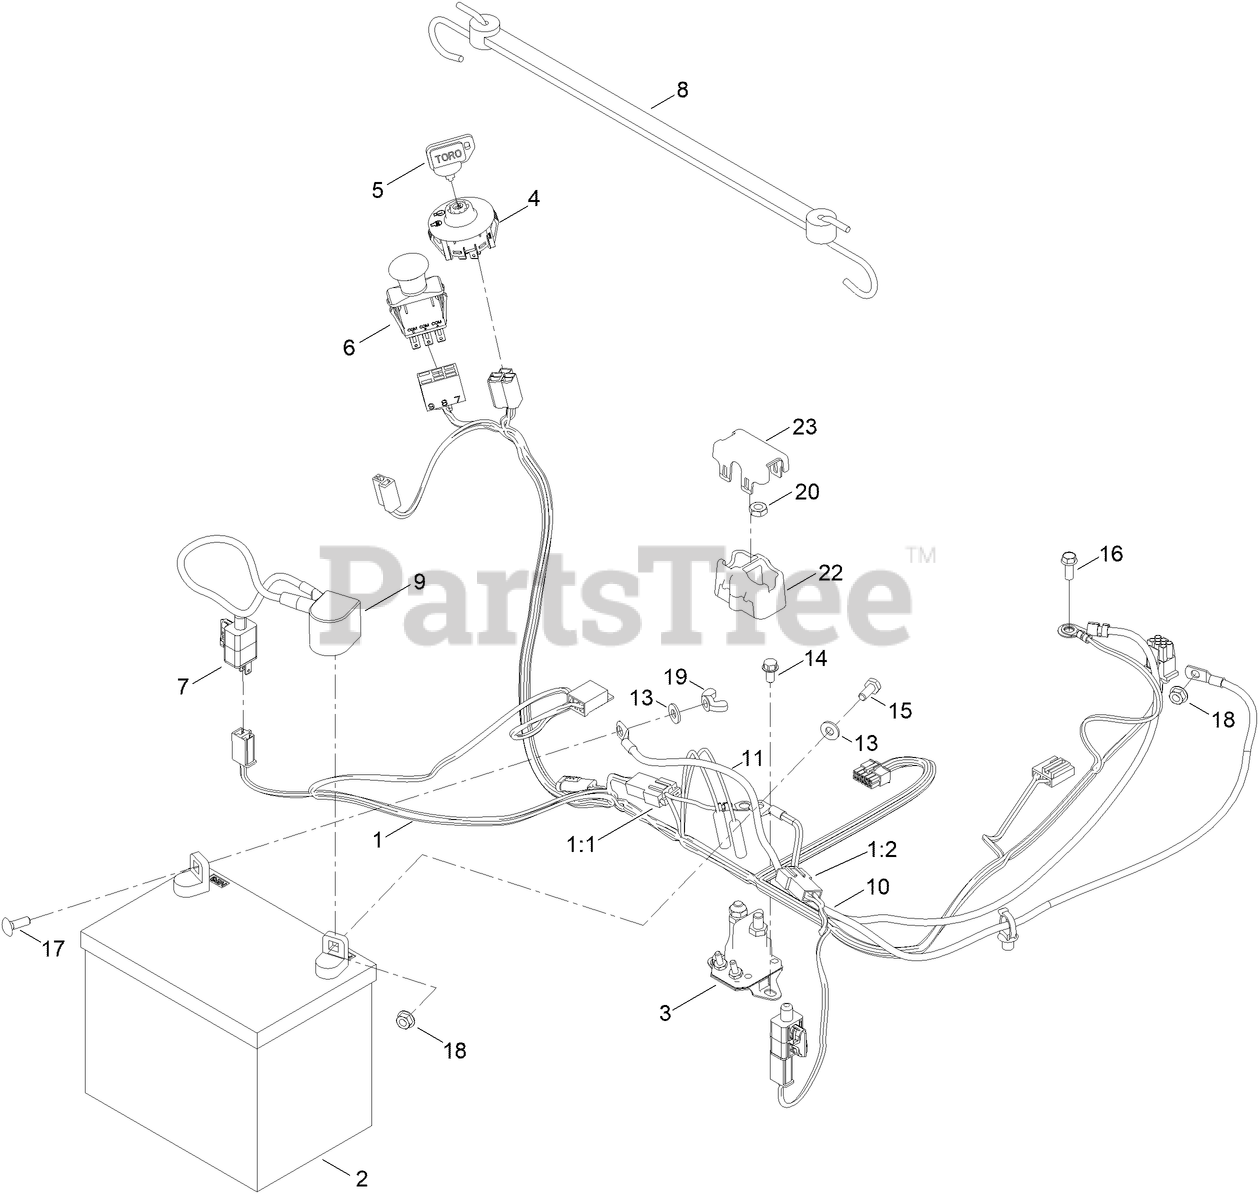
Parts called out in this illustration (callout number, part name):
1	HARNESS-WIRE
1:1	FUSE-BLADE, 15 AMP
1:2	FUSE-BLADE, 25 AMP
2	BATTERY
3	SOLENOID
4	SWITCH-IGNITION
5	KEY-IGNITION
6	SWITCH-PTO
7	SWITCH
8	STRAP-RUBBER
9	CABLE-BATTERY, POS
10	CABLE-BATTERY, RED (8 GAUGE)
11	CABLE-BATTERY, BLACK
13	WASHER-FLAT
14	SCREW-HWH
15	SCREW-HH
16	SCREW-HWH
17	BOLT-CARR
18	NUT-HF
19	NUT-WING
20	NUT-HJ
22	COVER-SOLENOID
23	CAP-SOLENOID
